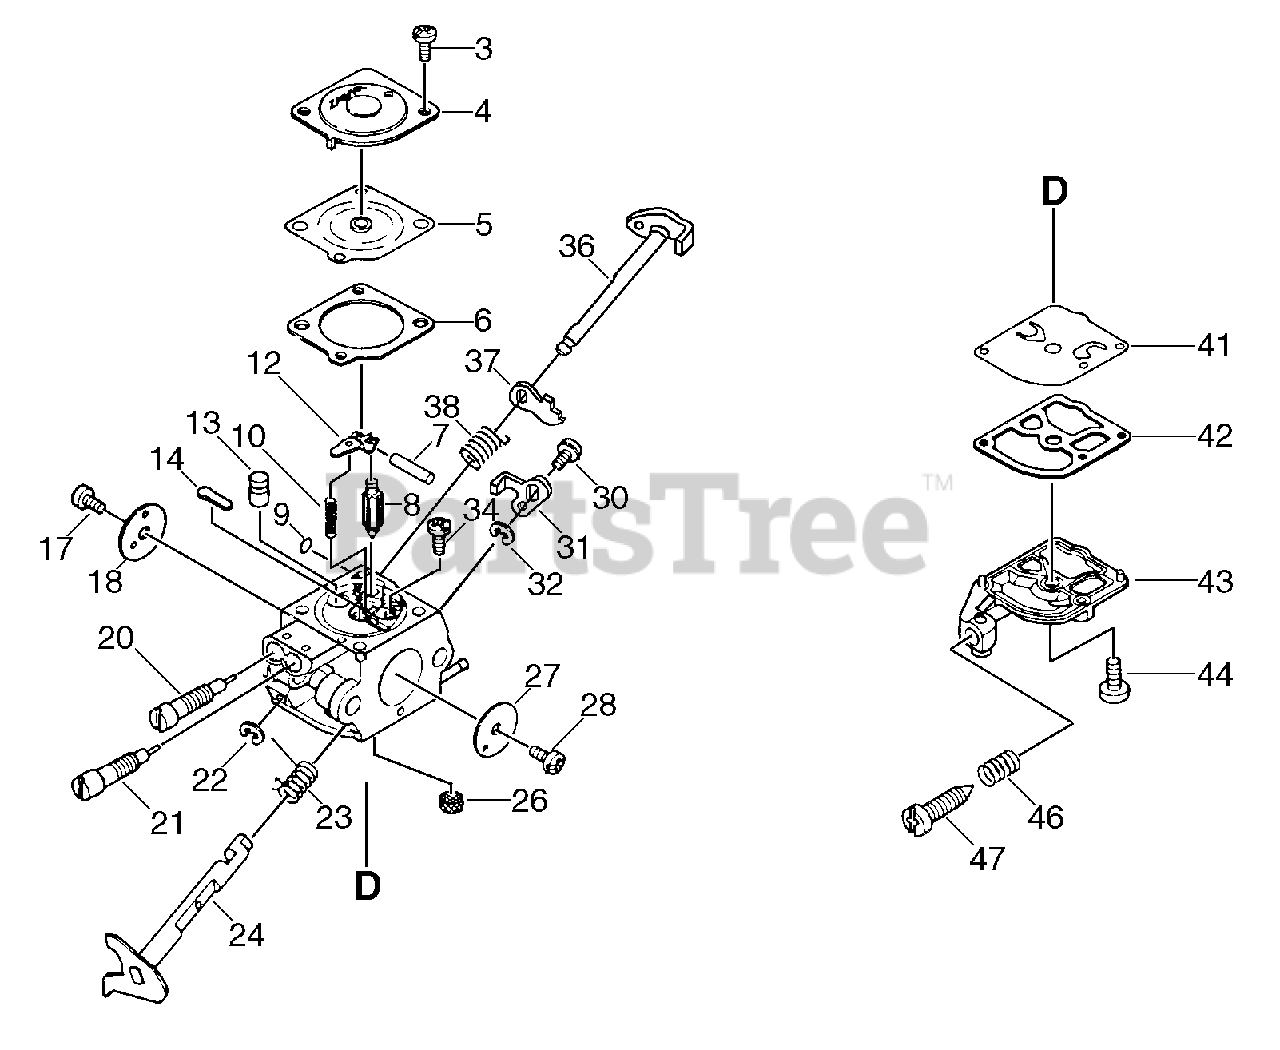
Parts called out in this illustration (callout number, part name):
4	COVER, METERING DIAPHRAGM
5	DIAPHRAGM, METERING
6	GASKET, METERING DIAPHRAGM
7	PIN, METERING LEVER
8	VALVE, INLET NEEDLE
9	PLUG, WELCH
10	SPRING, COIL
12	LEVER, METERING
13	NOZZLE, CHECK VALVE
14	PLUG, WELCH
17	SCREW 3×4.5
18	VALVE, CHOKE
20	NEEDLE, HIGH SPEED
21	NEEDLE, IDLE
24	SHAFT ASSY, THROTTLE
26	SCREEN, FUEL INLET
27	VALVE, THROTTLE
31	LEVER, THROTTLE
36	SHAFT, CHOKE
37	LEVER, CHOKE
38	SPRING, CHOKE RETURN
41	PUMP, DIAPHRAGM
42	GASKET, PUMP
43	COVER, PUMP
